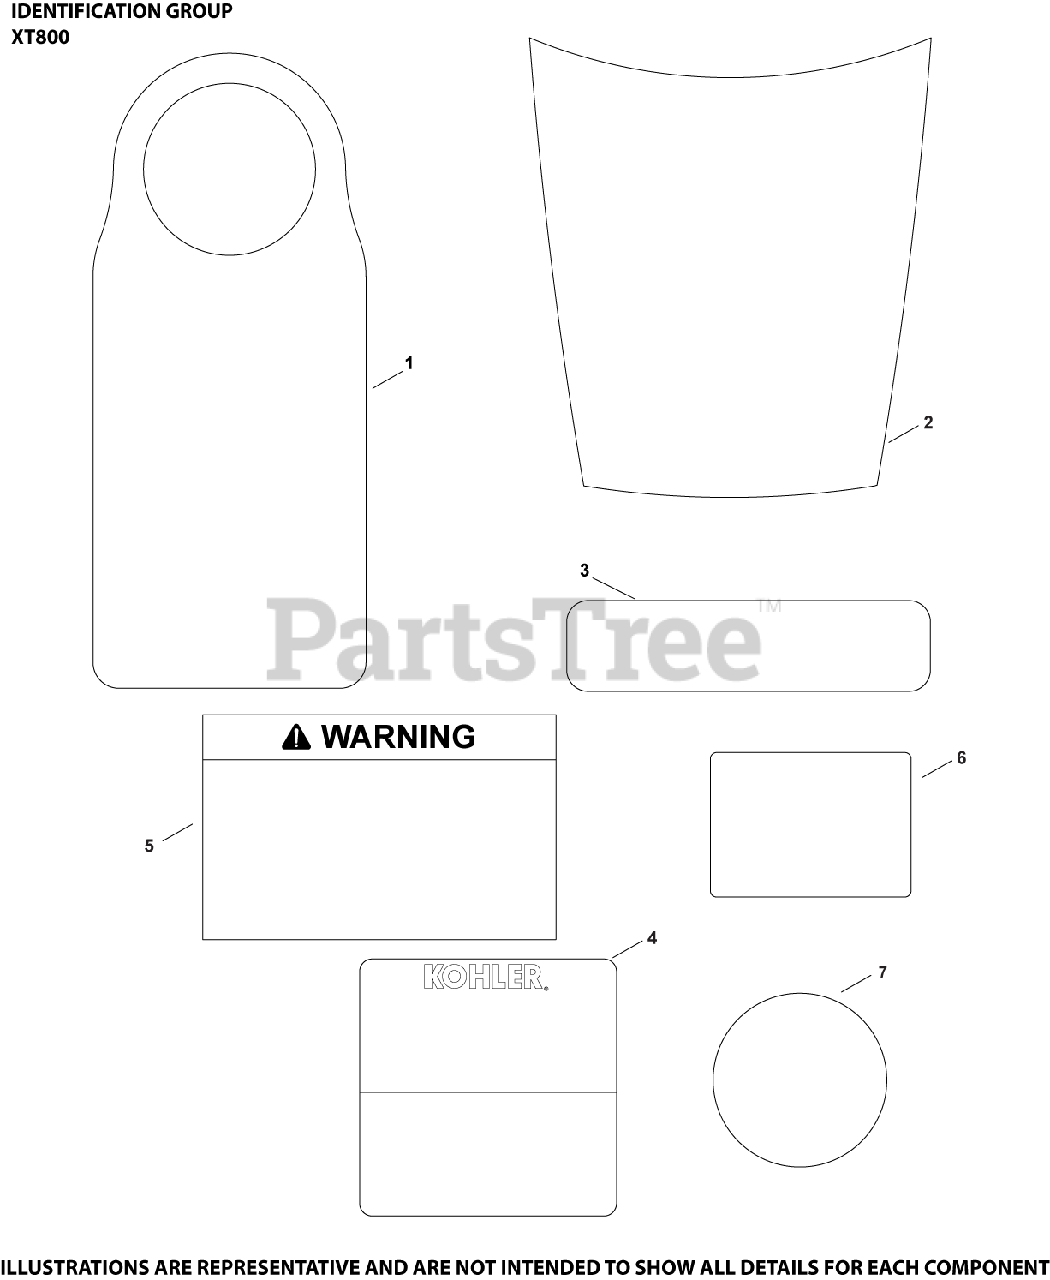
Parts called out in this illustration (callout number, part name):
1	TAG HANG OIL WARNING
2	DECAL, NAMEPLATE
4	NAMEPLATE, SERVICE
5	DECAL, WARNING
